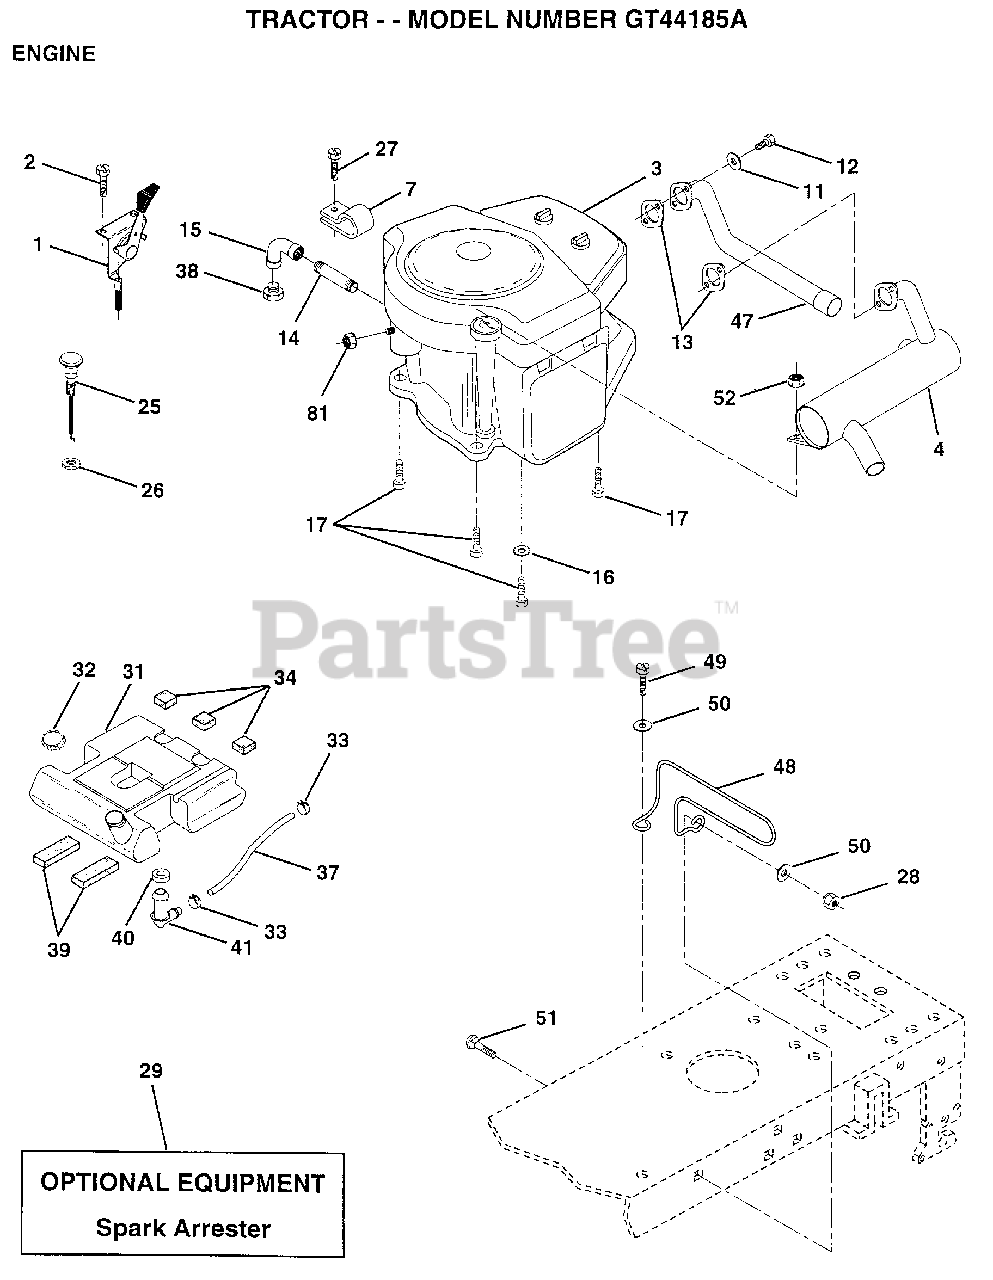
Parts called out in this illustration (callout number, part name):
1	CONTROL.TRTL.37
2	SCREW LT
3	ENGINE, BRIGGS
7	CLAMP.TUBE.DBL.EN
11	LOCKWASHER
13	GASKET MUFFLER
14	PIPE NIPPLE LT
15	ELBOW
16	LOCKWASHER
17	SCREW LT
25	"CONTROL.CHOKE.51"""
26	"NUT,KEPS 3/8-24IM"
27	"SCREW-TT,10-32 FL"
31	TANK FUEL REAR
32	CAP ASM FUEL
33	HOSE CLAMP
34	PAD-SPACER LT
37	FUEL LINE T
39	PAD IDLER TI
40	BUSHING OUTLET T
41	STEM.TANK.FUEL
47	EXHAUST TUBE T
48	MUFFLER GUARD
49	SCREW
50	WASHER HYT
51	BOLT D
52	NUT
81	NUT
